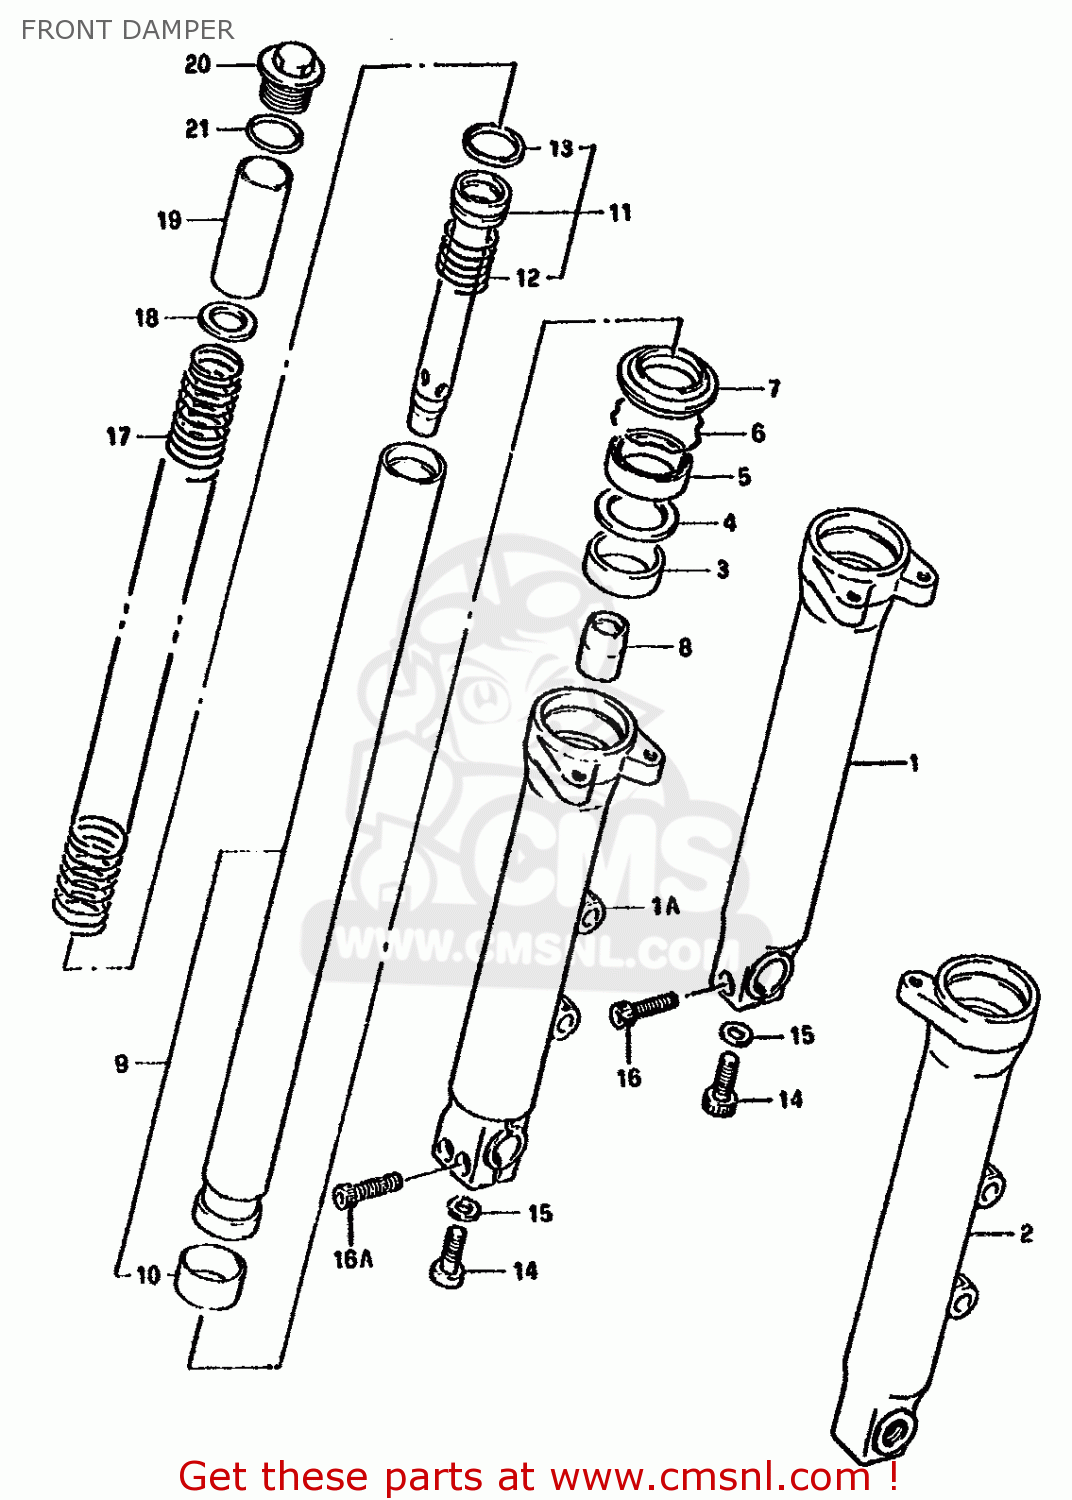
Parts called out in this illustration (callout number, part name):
1	TUBE,OUTER,RIGHT
1A	TUBE,OUTER RH
2	TUBE,OUTER LH
3	METAL,SLIDE
4	WASHER,FORK OIL SEAL
5	OIL SEAL,FRONT FORK
6	RING,OIL SEAL STOPPER
7	DUST SEAL,FRONT FORK
8	PIECE,OIL LOCK
9	TUBE,INNER
10	PISTON
11	CYLINDER
12	SPRING,REBOUND
13	RING,PISTON
14	BOLT,FORK CYLINDER(10X25)
15	GASKET (NAS)
16	BOLT
16A	BOLT, FRONT RH
17	SPRING,MAIN
18	GUIDE,SPRING
19	SPACER,SPRING
20	CAP,FORK
21	O-RING
